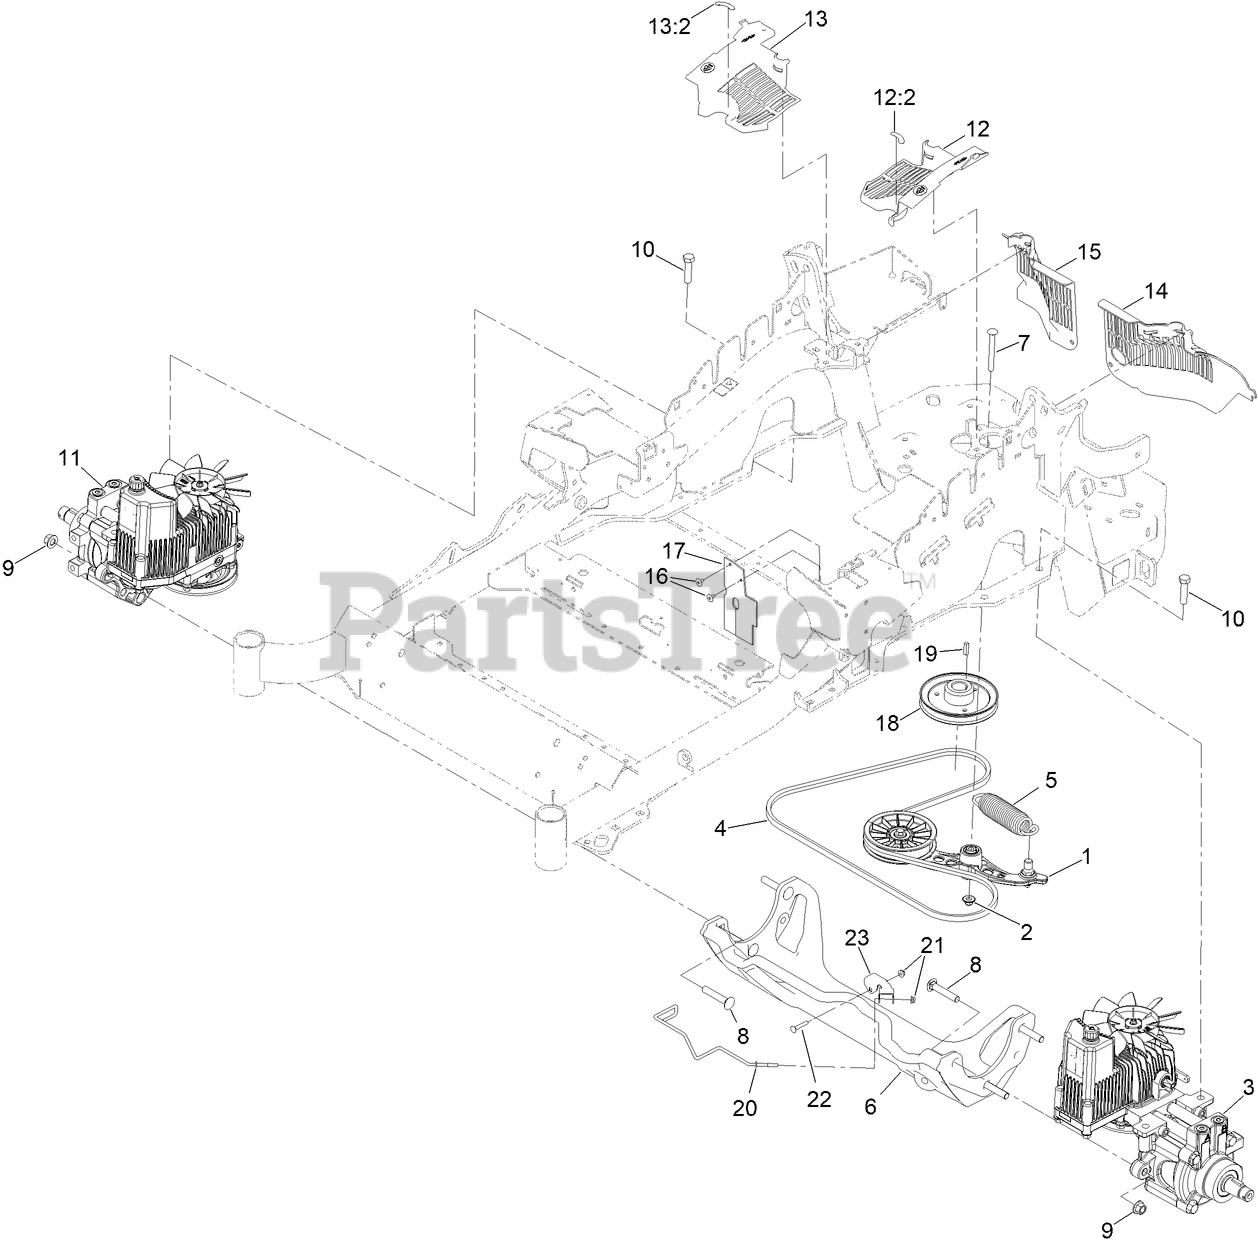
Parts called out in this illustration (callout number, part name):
1	PUMP IDLER ASM
2	NUT-FLANGE, NI
3	HYDRO-LH
4	BELT-V
5	SPRING-EXTENSION
6	CRADLE-HYDRO
7	BOLT-SHOULDER, CARRIAGE
8	SCREW-CARR
9	NUT-LOCK
10	SCREW-HH
11	HYDRO-RH
12	LH HYDRO GUARD ASM
12:2	DECAL-OIL, HYDRO
13	RH HYDRO GUARD ASM
13:2	DECAL-OIL, HYDRO
14	GUARD-HYDRO, REAR (LH)
15	GUARD-HYDRO, REAR (RH)
16	RIVET-POP
17	DEFLECTOR-AIR FLOW
18	SHEAVE, W/HUB
20	GUIDE-BELT
21	NUT-HF
22	SCREW-CARR
23	BRACKET-U
